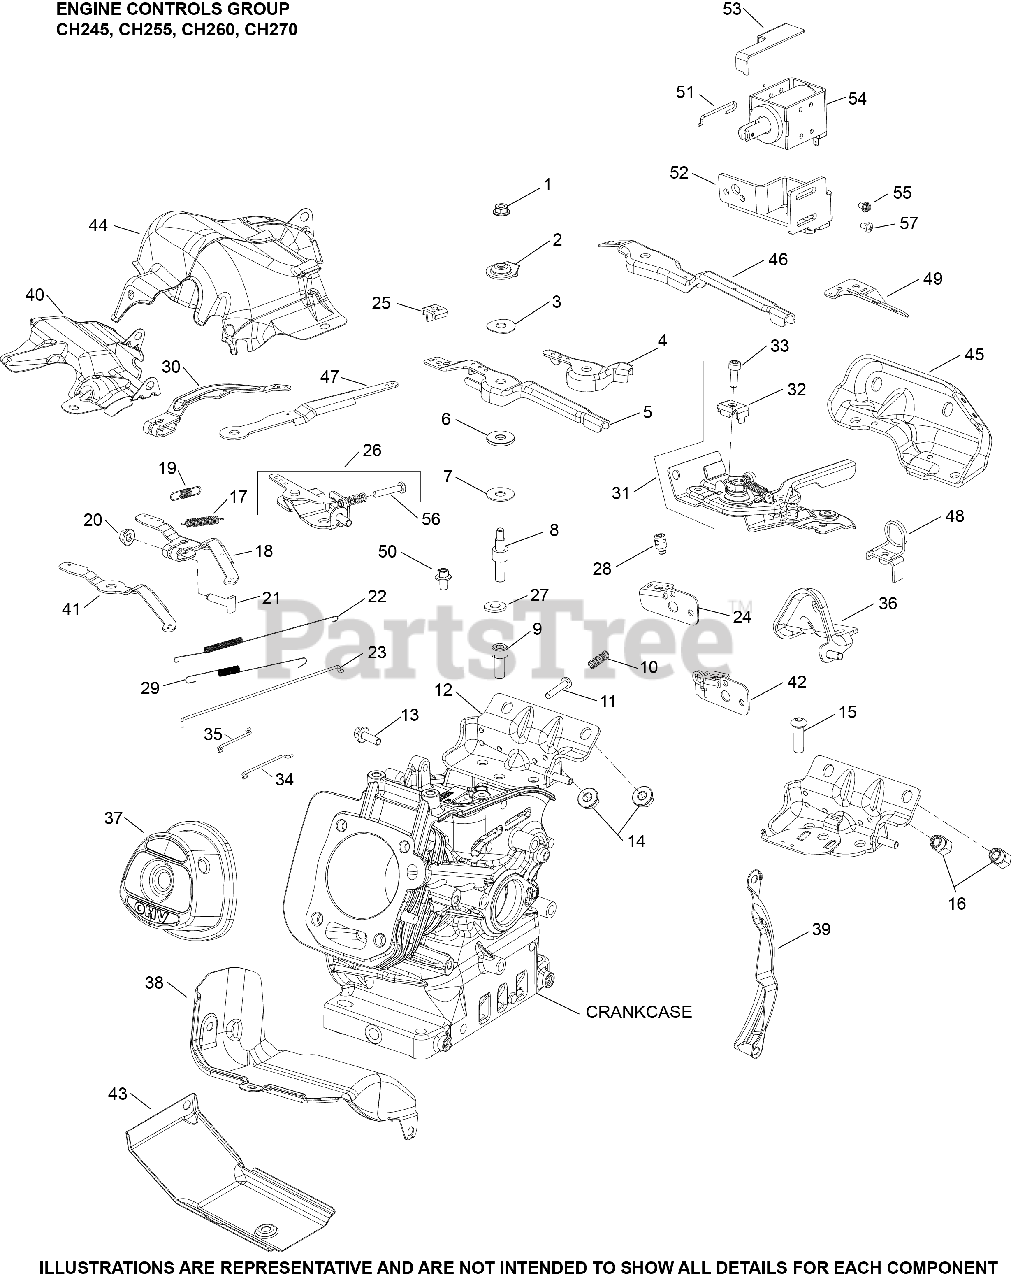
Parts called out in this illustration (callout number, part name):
1	NUT, HEX FLANGE LOCK (M6)
2	WASHER, CONTROL LEVER
3	WASHER, SPRING
5	LEVER, CONTROL THROTTLE
6	WASHER, NYLON CONTROL LEVER
7	WASHER, FLAT
8	STUD, CONTROL LEVER
9	SCREW, HEX SOCKET HD CAP (CKY)
10	SPRING, COMPRESSION
11	SCREW, SPEED ADJUSTING
12	BRACKET, FUEL AND CONTROLS
13	SCREW, M6 X18
14	NUT, FLG M8X1.25
18	KIT, GOVERNOR LEVER
19	SPRING, GOVERNOR
20	NUT, HEX FLANGE (M6) - USE 14 100 16-S
21	SCREW, RECTANGLE HEAD (M6)
22	SPRING, LINKAGE
23	LINKAGE, GOVERNOR
24	BRACKET, CABLE CLAMP
25	CLAMP, CABLE
